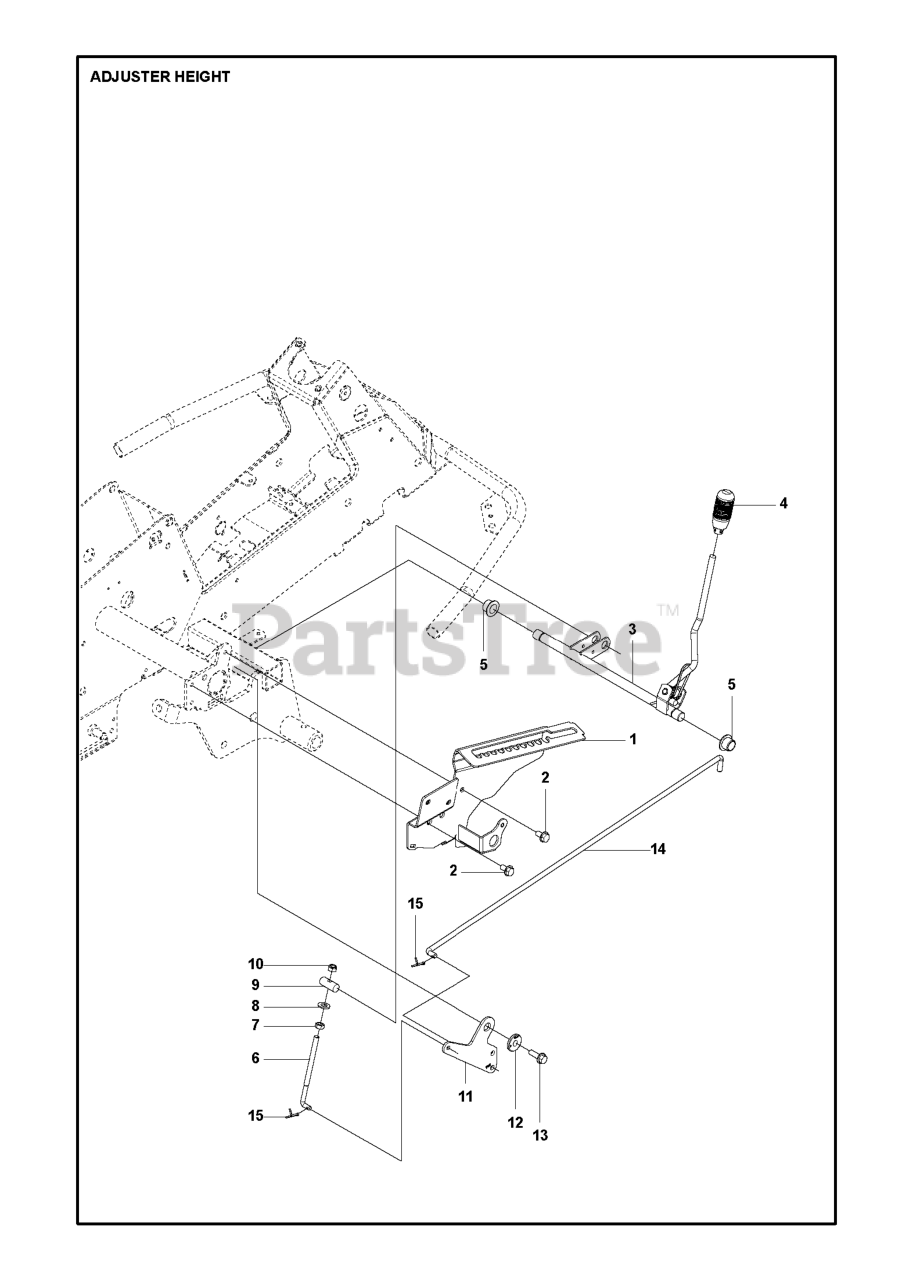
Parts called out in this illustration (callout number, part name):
3	HEIGHT ADJUSTER
5	BEARING FLANGE
7	NUT
8	WASHER
10	LOCKNUT M8
13	BOLT
14	CONNECTION ROD
